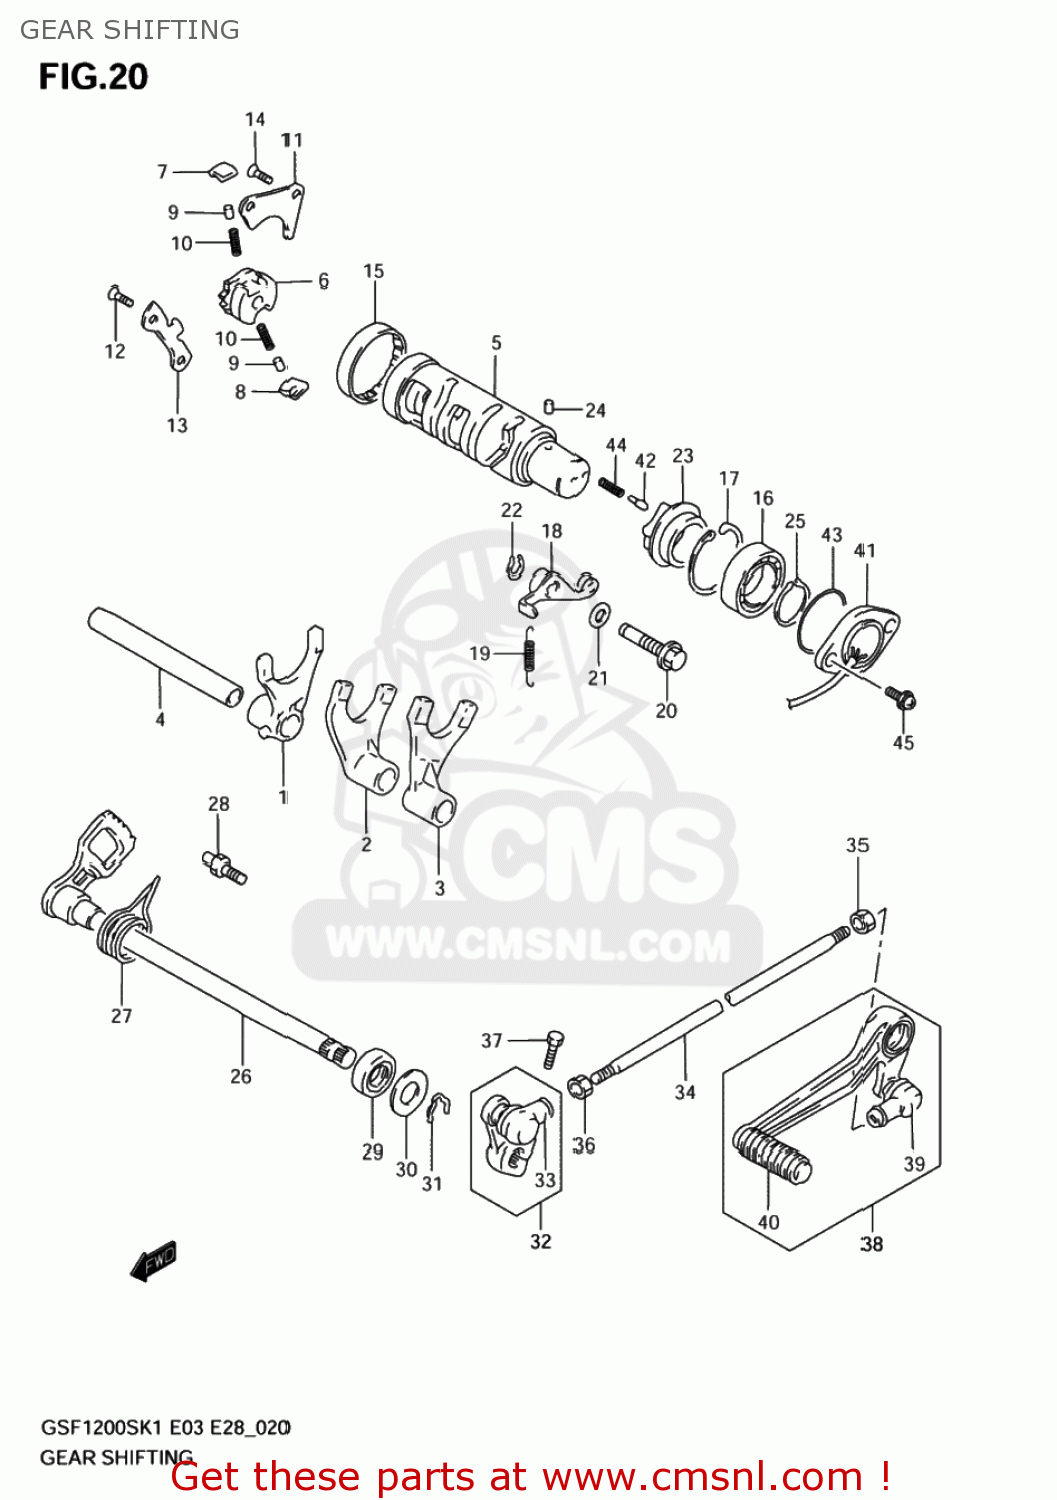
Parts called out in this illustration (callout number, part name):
1	FORK,GEAR SHIFT NO.1
2	FORK,GEAR SHIFT NO.2
3	FORK,GEAR SHIFT NO.3
4	SHAFT,GEAR SHIFT FORK(L:128)
5	CAM,GEAR SHIFT
6	GEAR,GEAR SHIFT CAM DRIVEN
7	PAWL,GEAR SHIFT NO.1
8	PAWL,GEAR SHIFT NO.2
9	PIN(5X8)
10	SPRING
11	LIFTER,GEAR SHIFT PAWL
12	SCREW(6X12)
13	GUIDE,GEAR SHIFT CAM
14	SCREW(6X12)
15	BEARING(43X49X12)
16	BEARING
17	CIRCLIP
18	STOPPER,GEAR SHIFT CAM
19	SPRING
20	SHAFT,GEAR SHIFT CAM STOPPER
21	GASKET(10X14X3.6) (NAS)
22	CIRCLIP
23	PLATE,STOPPER
24	PIN
25	CIRCLIP
26	SHAFT,GEAR SHIFT
27	SPRING
28	STOPPER,GEAR SHIFT ARM
29	OIL SEAL
30	WASHER (12.5X26X1.6)
31	CIRCLIP,12 MM
32	ARM,GEAR SHIFT LINK
33	COVER,DUST
34	ROD,GEAR SHIFT LINK
35	NUT
36	NUT
37	BOLT
38	LEVER ASSY,GEAR SHIFT
39	COVER,DUST
40	RUBBER,GEAR SHIFT PEDAL
41	BASE ASSY,GEAR SHIFT TERMINAL
42	PIN(5X15.5)
43	O RING(D:2.4,ID:35.5)
44	SPRING
45	SCREW
